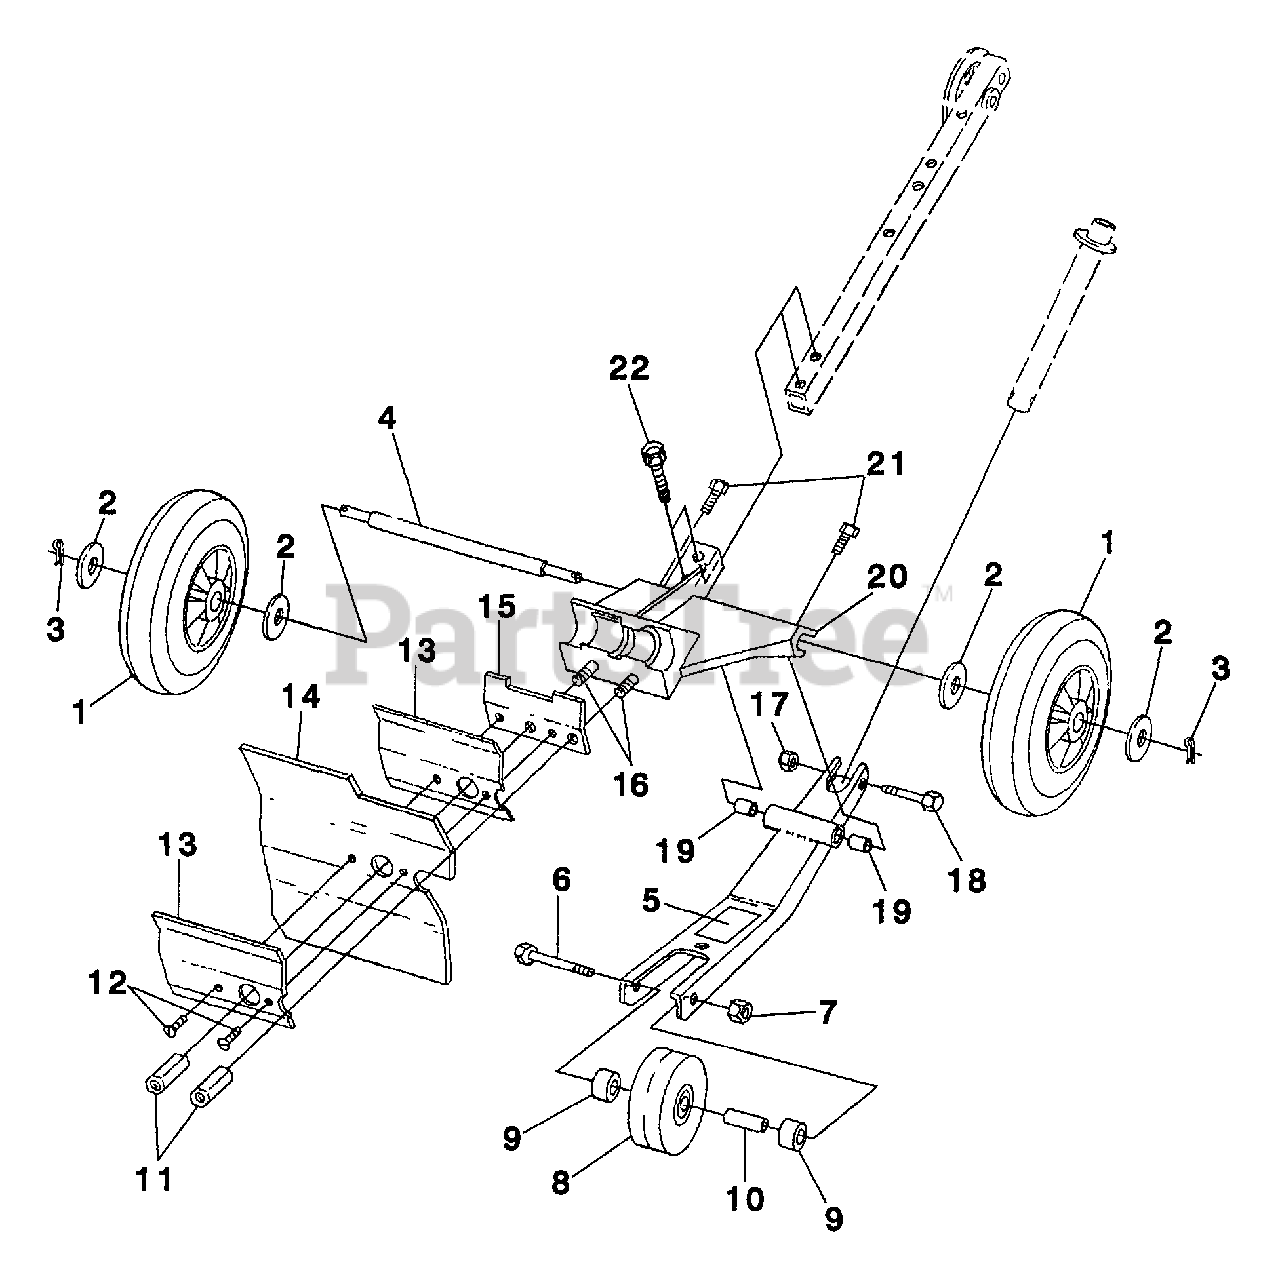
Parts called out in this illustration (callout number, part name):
1	Wheel 8"
2	Flat Washer
3	Cotter Pin
5	Warning Decal
6	Bolt 3/8-16
7	Nut 5/16-18
8	Wheel 4"
9	Wheel Bushing
10	Wheel Spacer
11	Hex Coupling Nut
12	Screw 10-32 x 1/2
13	Shield Clamp
14	Reinforced Rubber Shield
15	Handle Clamp
17	Nut 5/16-18
18	Screw 5/16 x 2 1/2
19	Oilite Bearing
20	Chassis Assembly
21	Hex Bolt 5/16-18
22	Bolt 5/16-18 x 2.25
